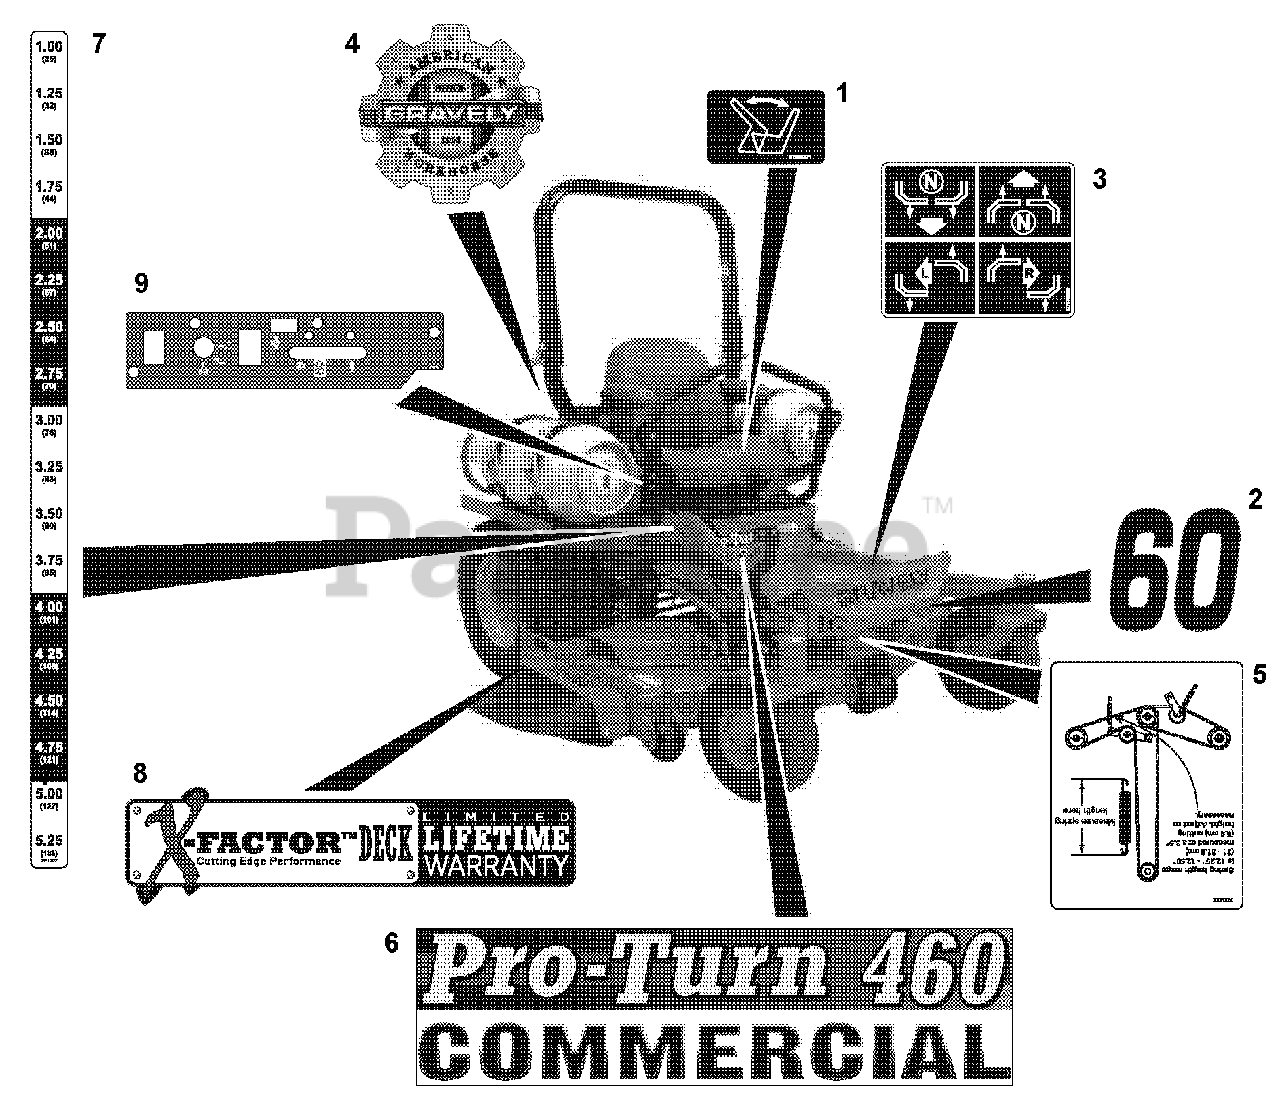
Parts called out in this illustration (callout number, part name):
1	Decal, Seat Release
2	Decal, 60 (992237)
3	Decal, Instructional Steering
4	Decal, Gravely Heritage
5	Decal, Belt Routing (992237)
6	Decal, Pro-Turn 460 (992237)
7	Decal, PT-400 Height of Cut
8	Decal, X-Factor Deck
9	Decal, Control Panel
